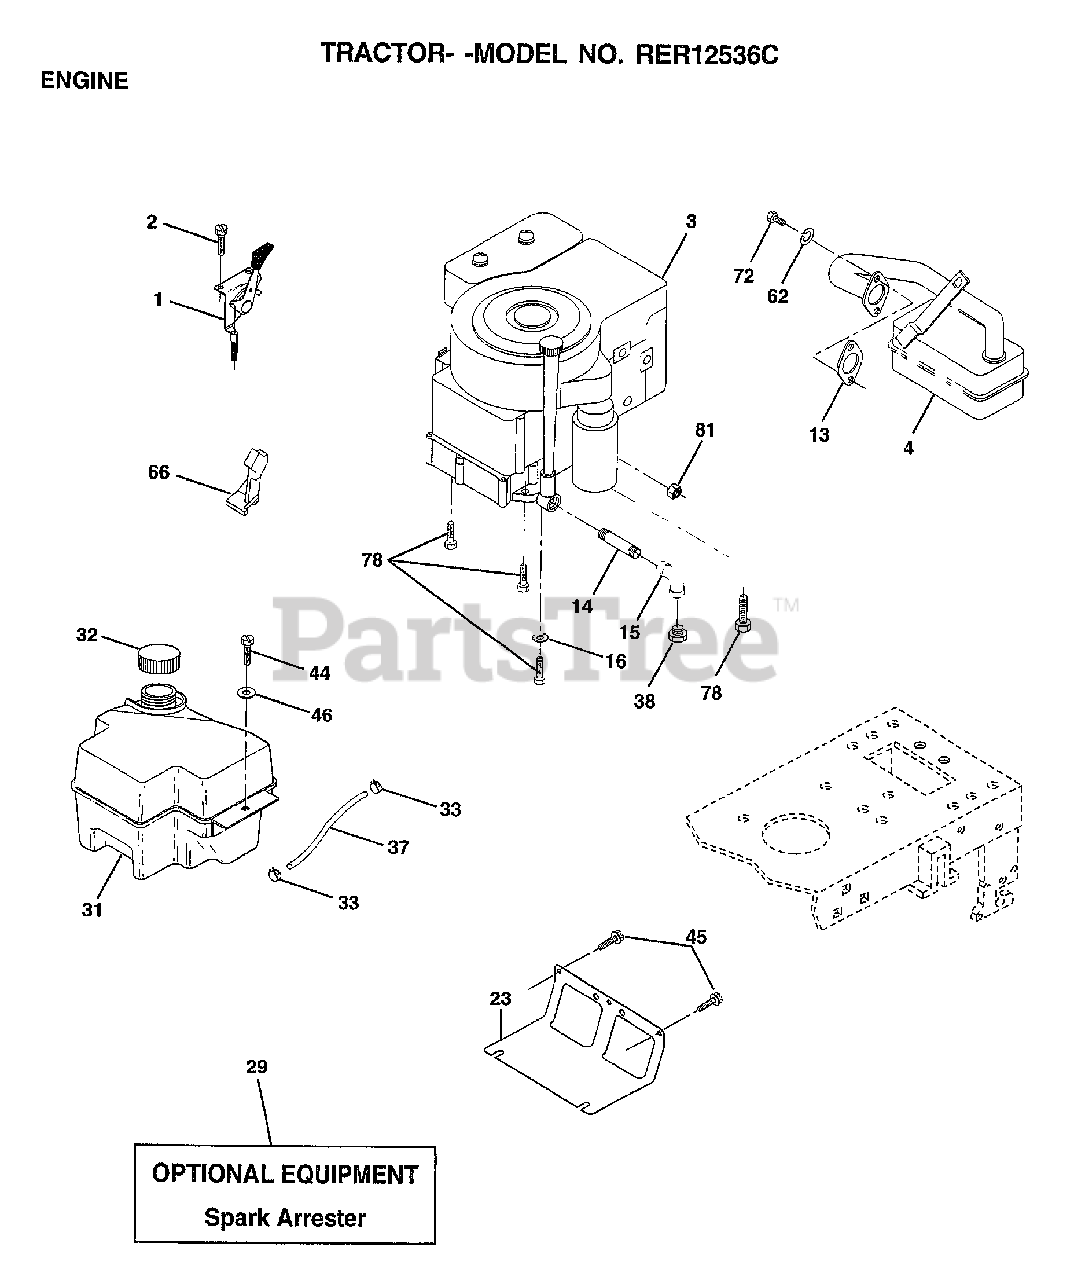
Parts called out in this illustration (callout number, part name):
1	CONTROL.THTL.23.5
2	SCREW LT
4	MUFFLER
14	PIPE NIPPLE
15	ELBOW
16	LOCKWASHER
23	SHIELD BROWNING
31	TANK.FUEL.FRONT.
32	CAP ASM FUEL
33	HOSE CLAMP
37	LINE FUEL
44	SCREW
45	SCREW
46	WASHER
62	LOCKWASHER
66	"STOP,DASH THROTT"
72	SCREW LT
78	SCREW
81	NUT
